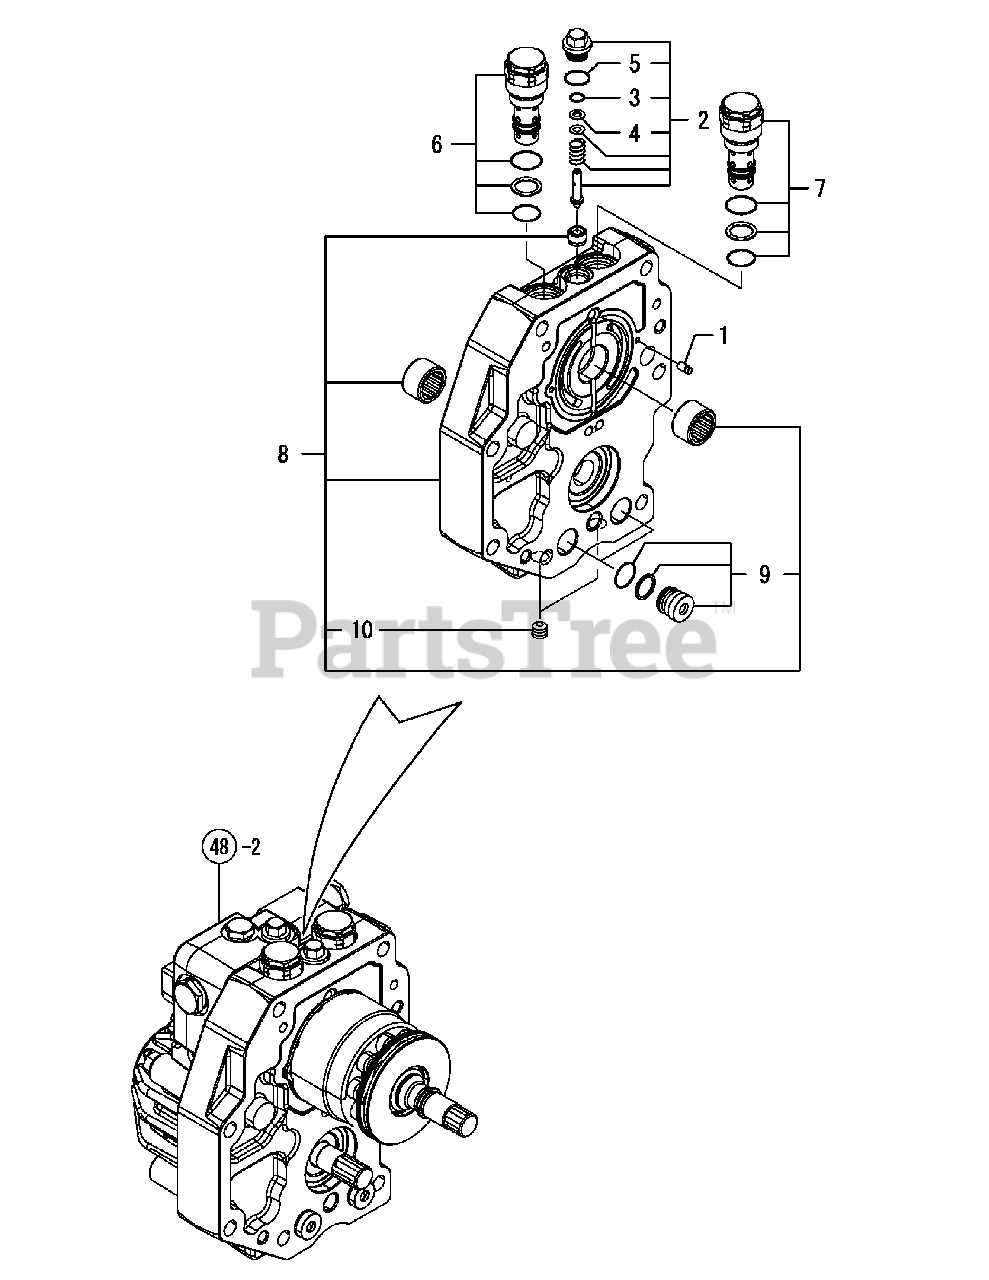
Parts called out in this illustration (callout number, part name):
1	Pin, Knock 3.5
2	Relief Comp., Imple
4	Washer 5, Polished
5	O-Ring 1A P-12.0
6	Cr Valve F Cmp
7	Cr Valve R Cmp
8	Case Assy, Center
9	Body Cmp, Suction
10	Plug Pt1/8,Screw
